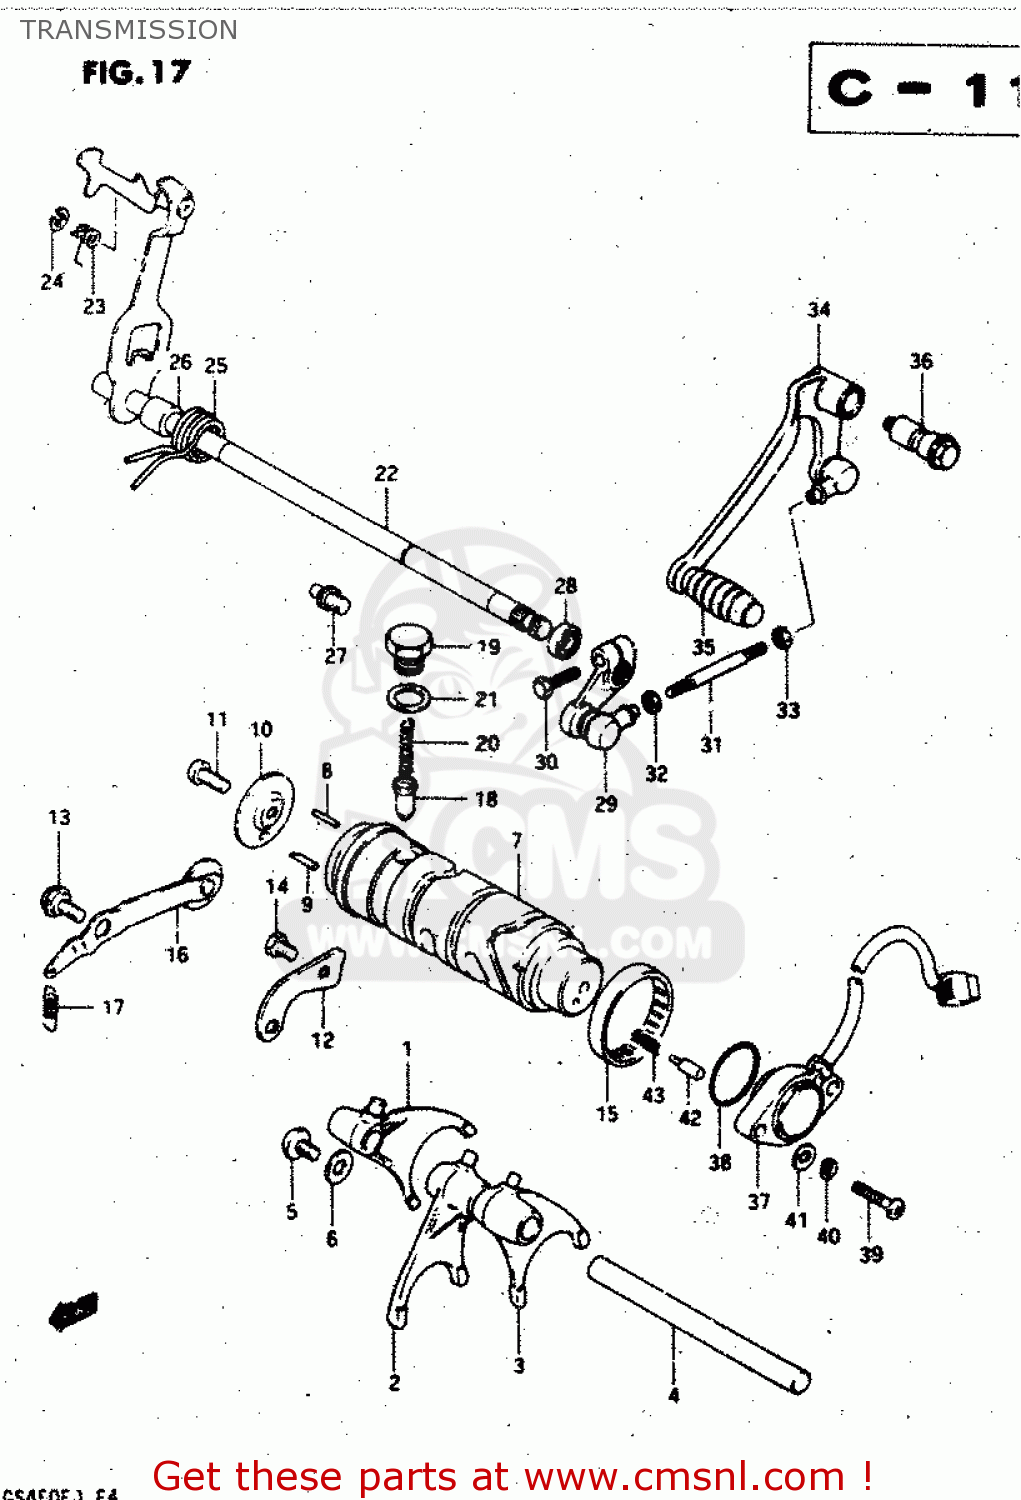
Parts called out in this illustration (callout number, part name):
1	SHAFT,COUNTER
2	SHAFT,COUNTER
3	GEAR,2ND DRIVE(NT:18)
4	GEAR,THIRD DRIVE
5	GEAR,FIFTH DRIVE
6	GEAR,SIXTH DRIVE
7	WASHER
8	CIRCLIP
9	BEARING(25X62X17)
10	C-RING
11	ROLLER BEARING (20X34X2
12	PIN
13	PLATE,COUNTERSHAFT BEARING
14	SCREW
15	SHAFT,DRIVE
16	GEAR,FIRST DRIVEN
17	WASHER
18	GEAR,SECOND DRIVEN
19	WASHER
20	GEAR,SECOND DRIVEN
21	BUSHING
22	CIRCLIP
23	GEAR,THIRD DRIVEN
24	WASHER,LOCK
25	WASHER,LOCK
26	CIRCLIP
27	GEAR,FOURTH DRIVEN
28	WASHER,LOCK
29	WASHER
30	CIRCLIP
31	GEAR,5TH DRIVEN(NT:25)
32	GEAR,SIXTH DRIVEN
33	C-RING
34	SEAL,OIL(32X62X7)
35	ROLLER BEARING (20X34X1
36	SEAL,OIL(32X62X5.5)
37	SPROCKET,ENGINE(NT:16)
38	NUT
39	WASHER
40	CHAIN ASSEMBLY,DRIVE
